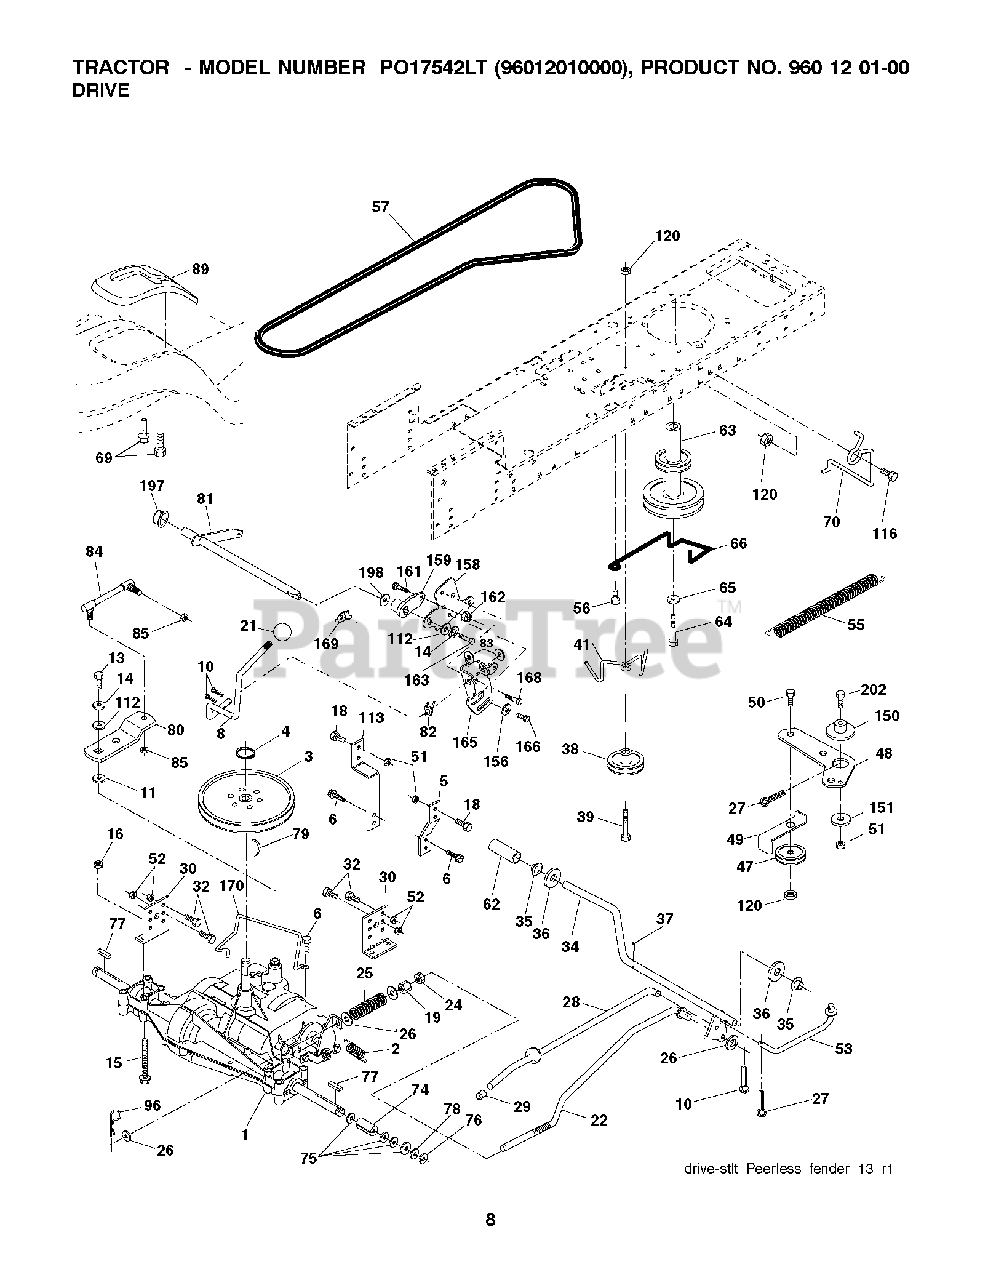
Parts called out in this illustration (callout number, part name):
1	Poulan TBD
2	SPRING,BRAKE RETURN
3	PULLEY TRANS
4	RETAINING RING LT
5	STRAP TORQUE
6	SCREW 5/16"
8	ROD SHIFT FENDER ADJUST LT
10	PIN COTTER
11	WASH-SHFT PLT LT
13	Bolt, 1/4-20 unf Grade 8 w/Patch
14	LOCKWASHER
16	NUT.71038.31-18.HEX.NYLOCK
19	NUT
21	KNOB T (1/2-HOLE)
22	ROD BRAKE
24	NUT
25	SPRING ROD LT
27	COTTER PIN
28	ROD, PARKING BRAKE
29	PLUNGER CAP
30	BRKT, TRNSXLE MNT 20"
32	BOLT
34	SHAFT, FOOT PEDAL
35	BEARING.NYLON
36	WASHER LT
37	Drive Pin, 3/16 X 1"
38	PULLEY IDLER COMPOSITE
41	KEEPER, BELT IDLER
47	Idler Pulley
48	BELLCRANK, CLUTCH
49	RETAIN BELT
50	BOLT.3/8-16X1.50
51	LOCKNUT
52	LOCKNUT
53	LINK.CLUTCH.7.66.2005
55	SPRING, RETURN LT
56	SCREW.3/8-16
57	BELT, V GROUND DRIVE 95 25
63	ENGINE PULLEY
64	BOLT HEX 7/16-20X4-1/4"
65	LOCKWASHER
66	KEEPER BELT ENGINE
69	SCREW.HI-LO.CONSOLE
70	KEEPER BELT ENG
74	SPACER AXLE
76	E-RING LT
77	SQUARE KEY
79	KEY.WOODRUFF
80	ARM SHIFT
81	SHAFT ASM CROSS TAPERED PMST/2
82	SHIFT SPRING
83	WASHER
84	LINK.TRANSAXLE.PMST/DANA.20"
85	NUT LOCK CENTER 1/4 -28 FNTHD
89	CONSOLE SHIFT STLT
112	WASHER LT
113	STRAP TORQUE LH LT
120	NUT LOCK FLG 3/8-16 UNC
150	SPACER, RETAINER
151	WASHER 12/32X2X10GA
156	WASHER.SRRTD.5/16
158	BRACKET
159	HUB.SHIFT
161	BOLT
162	NUT.CROWNLOCK.1/4
165	RP BRACKET
168	BOLT.SHOULDER.5/16-18X
169	PLATE.FASTENING.CROSS.SHAFT
170	KEEPER BELT T/A
197	NYLINER SNAP 5/8" ID
198	WASHER.NYL.7/8IDX.105"HYD CR
202	BOLT
